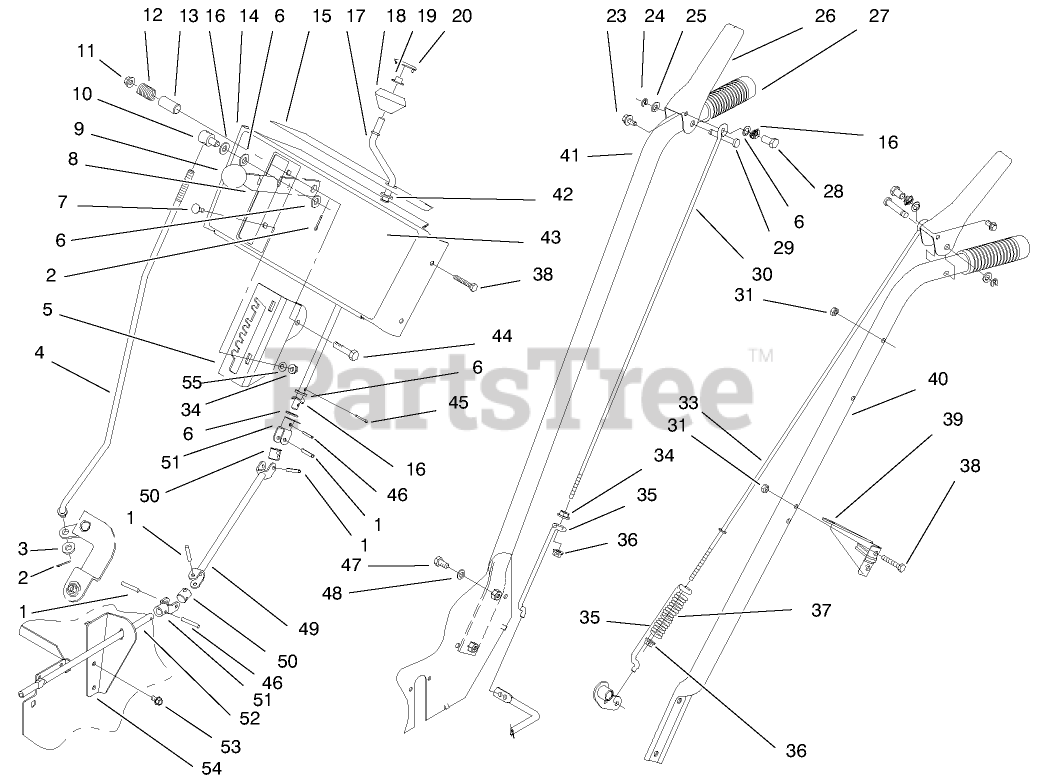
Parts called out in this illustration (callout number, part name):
1	PIN-SPRING
2	PIN-COTTER
3	WASHER-FLAT
4	ROD - SHIFT
5	MOUNT-SPEED SELECTOR
6	WASHER-FLAT
7	SCREW-CARR
8	SELECTOR-SPEED
11	NUT-HF
13	SPACER
15	DECAL-ESCUTCHEON BACK (INTL)
15	DECAL-ESCUTCHEON BACK (DOM)
16	WASHER-SPRING
17	ROD - CHUTE CRANK
18	KNOB-CONTROL, CHUTE
19	NUT-PUSH
20	COVER-KNOB
23	SCREW-HHF
24	RING-CLIP
25	WASHER-PLAIN
26	HANDLE-CONTROL
28	POST-MOUNTING, LINKAGE
29	PIN-LEVER, CONTROL
30	ROD-UPPER ENGAGE AUGER
31	NUT-LOCK, NI
33	ROD - UPPER TRACTION
34	NUT-HF
35	ROD - LOWER TRACTION
36	NUT-HHF
37	SPRING
38	SCREW-HH
39	BKT-UPPER CRANK
43	Decal-Control Panel
44	SCREW-HH
45	PIN-COTTER
46	PIN-SPRING
47	SCREW-HWHTF
48	WASHER-BELLEVILLE
49	WA - CLEVIS ROD
50	BLOCK - PIVOT
51	WA - CLEVIS MOUNT
52	ROD - CHUTE CONTROL
53	SCREW-HWH
54	BRKT-LOWER CRANK ROD
55	WASHER-FLAT
